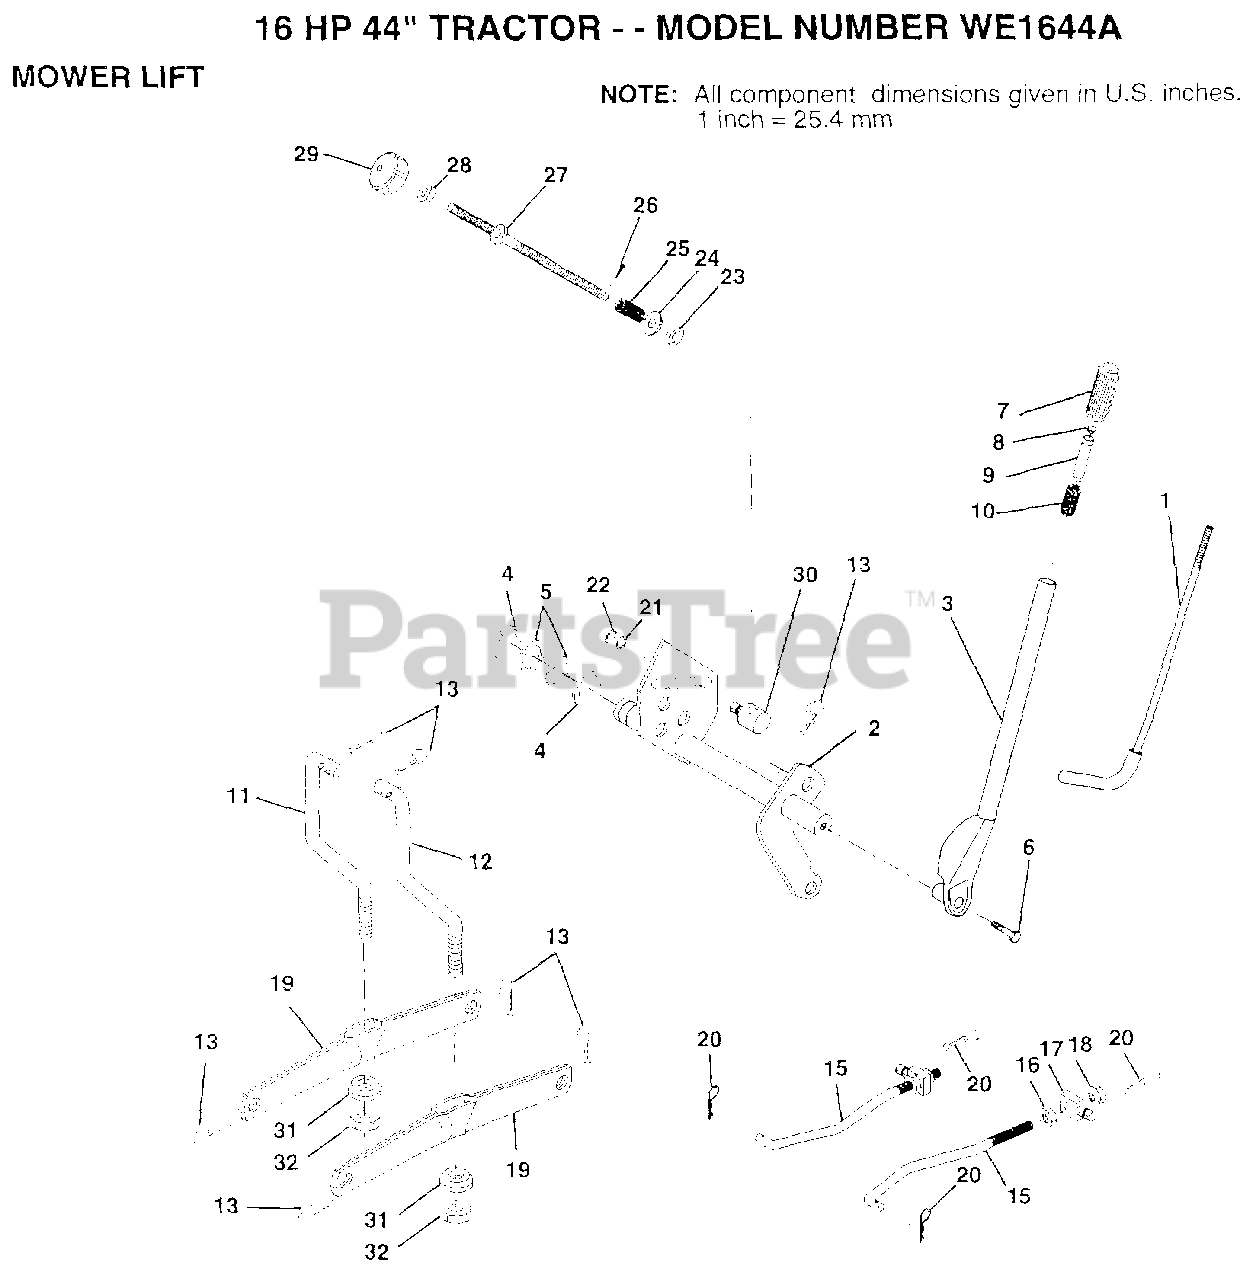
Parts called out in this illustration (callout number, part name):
1	LEVER ROD LT
2	SHAFT LIFT W/IND
4	E-RING
5	WASHER
6	"BOLT,HEX"
7	GRIP
10	SPRING T
11	LINK LIFT LH
12	LINK LIFT RH
15	LINK.FRONT
16	NUT
17	TRUNION
18	NUT.LK.W/WSH.1/2.
19	ARM SUSP REAR
20	RETAINER.SPRING
21	WASHER
22	KLIP RING
23	NUT T
24	WASHER
25	SPRING T
27	ROD LIFT LT
28	NUT
29	KNOB INF 3/8-16
30	TRUNION LT
31	BEARING PVT LH
32	NUT.LOCK.3/8-24
